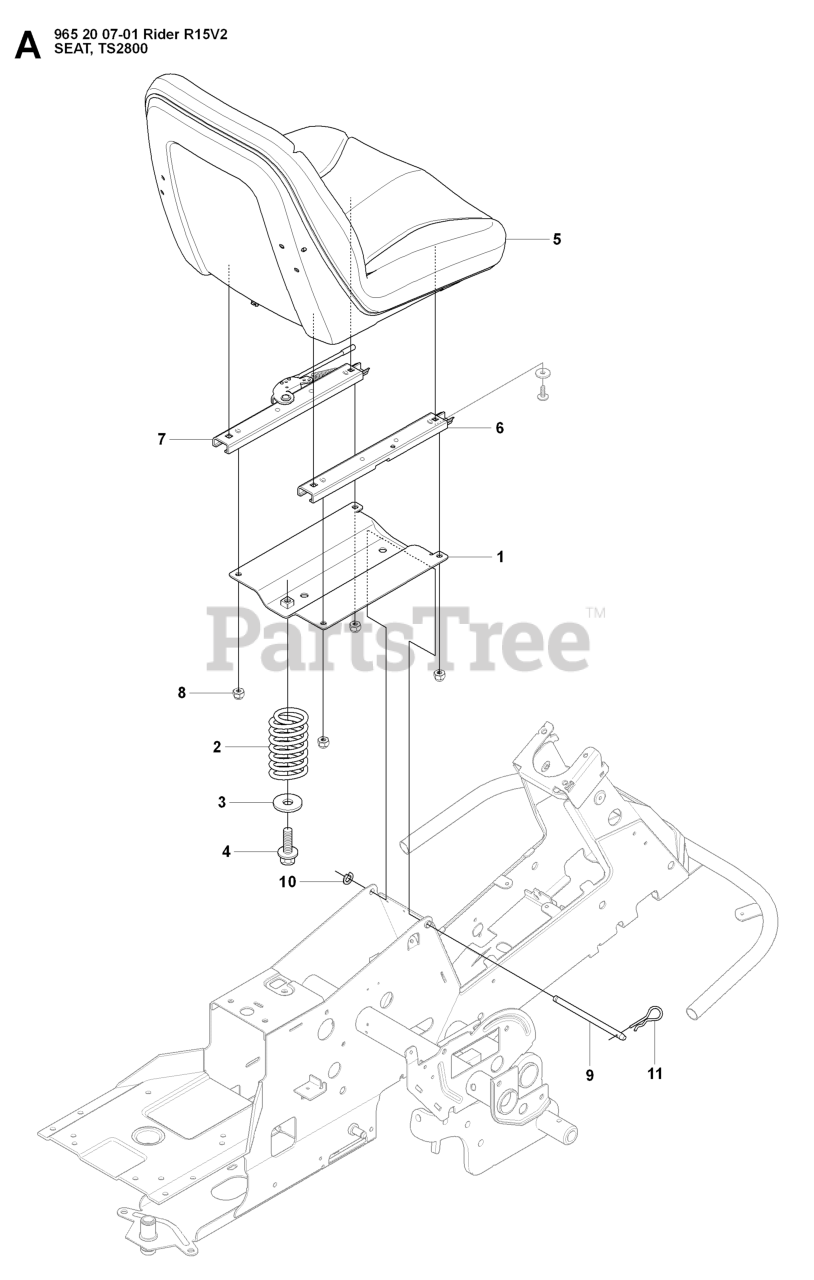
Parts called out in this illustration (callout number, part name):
2	SEAT SPRING
4	Screw M10x25
5	SEAT
8	LOCKNUT M8
10	RETAINING RING SGA 10
